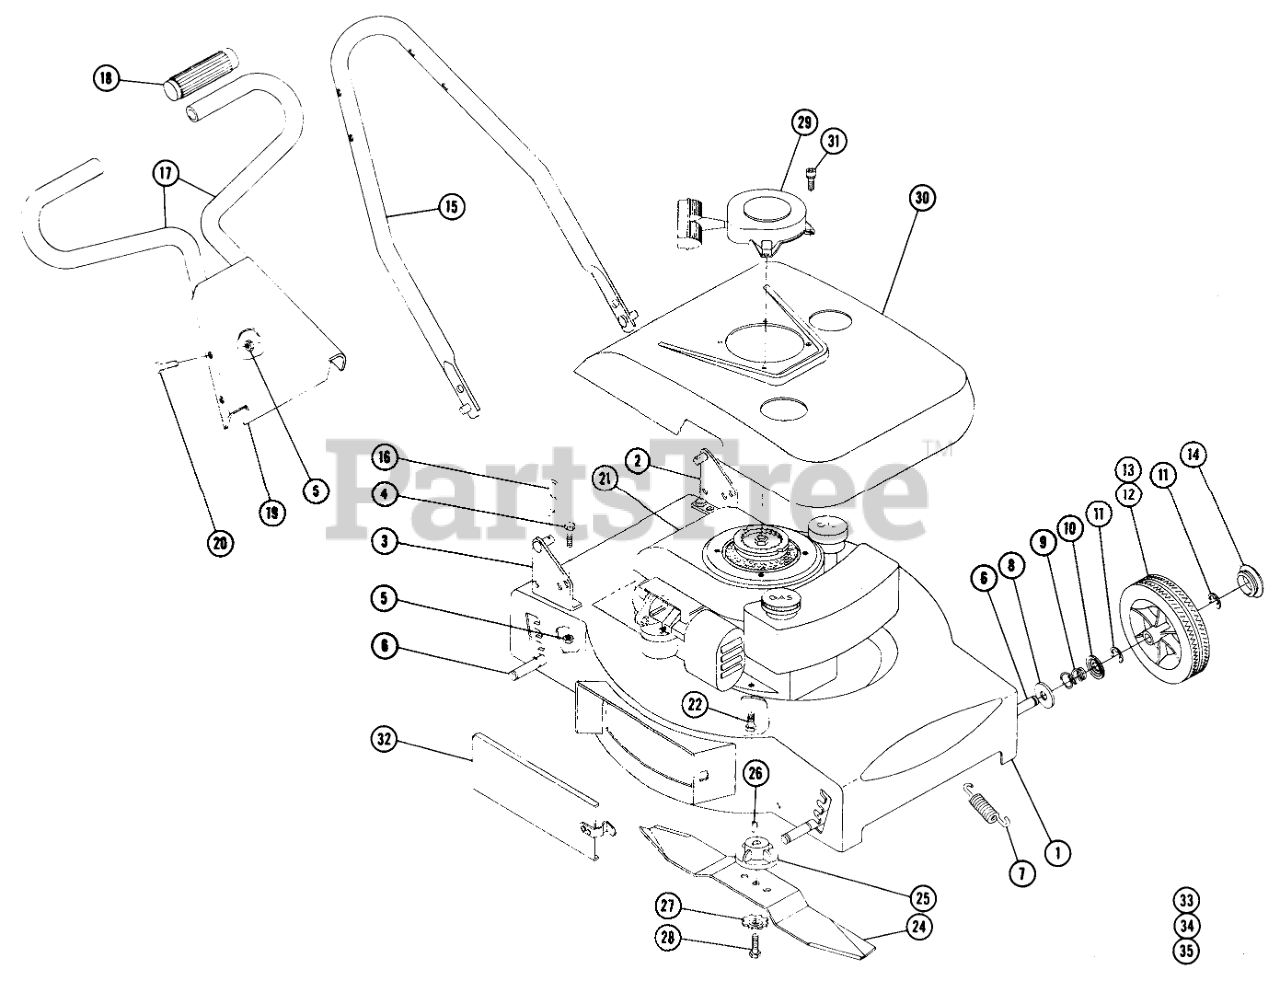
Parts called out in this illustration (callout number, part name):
1	Ass-y. Deck
2	Ass-y. Bracket-Handle L.H.
3	Ass-y. Bracket-Handle R.H.
4	Bolt 5/16-18 x
5	Nut-Nylok
6	Shaft-Axle
7	Spring-Idler
8	Washer
9	Spring-Wheel
10	Washer-Cup
11	Lock Rod
12	Wheel-Rear 8"
13	Wheel-Front 7"
14	Hubcap
15	Ass-y. Handle-Lower
16	Hairpin
17	Handle-Upper
18	Grip-Handle
19	Cover-Handle
20	Bolt-Hex. 5/16-18 x 1
21	Pivot Bushing
22	Bolt-Flg. 5/16-18 x 1
24	Blade 18" Rotary
25	Drive Blade
26	WOODRUFF KEY
27	WASHER
28	Bolt 3/8-24 x 1 1/4 Nylok
29	Ass-y. Starter-Recoil
30	Shroud-Engine
31	Screw & Lockwasher 1/4-28 x 9/16
32	Ass-y. Plate-Mulching
33	4XC6485 GIS ROTARY
34	Decal-Reo
35	Decal-Caution
